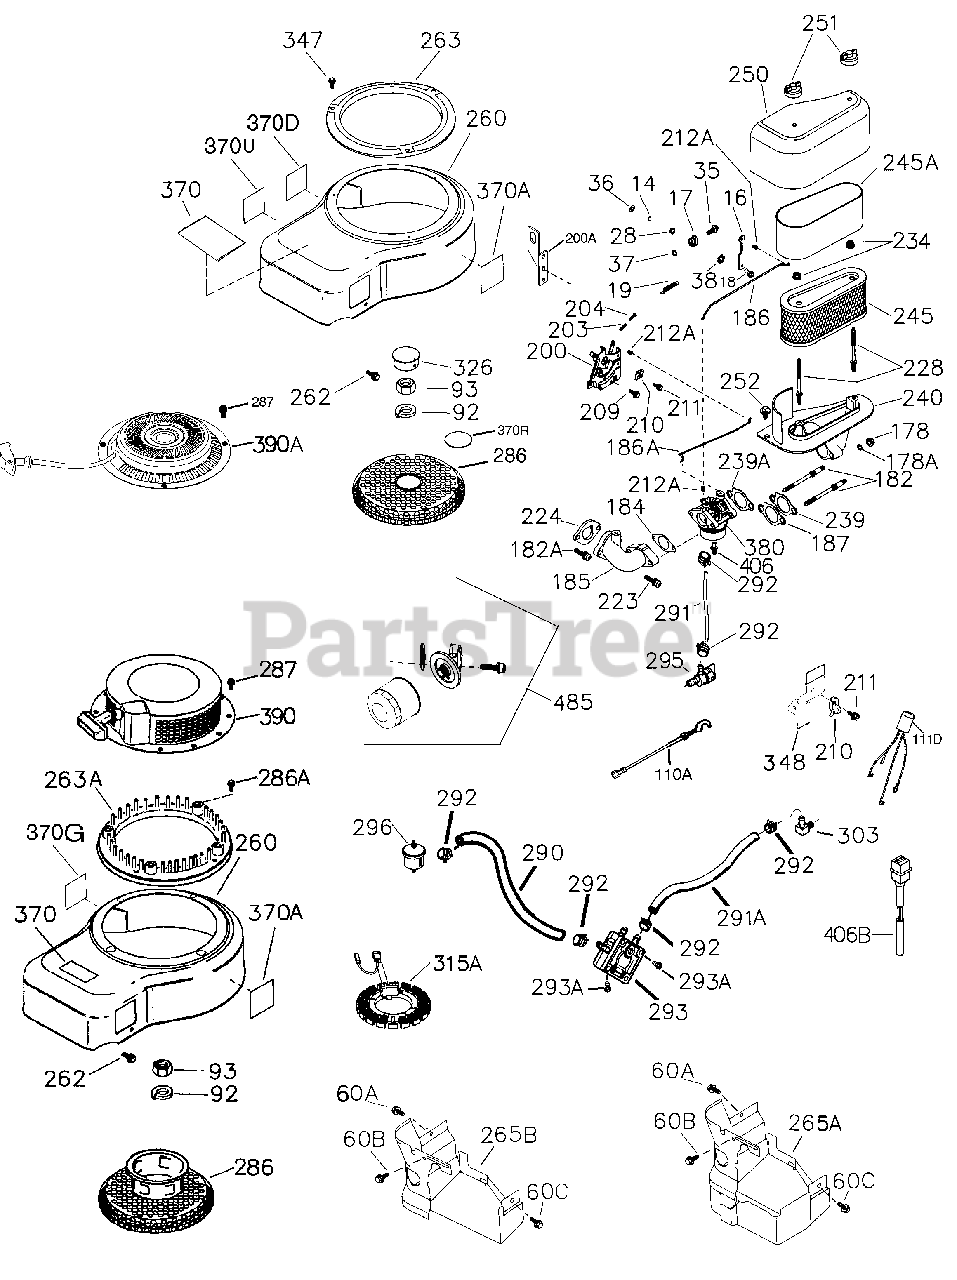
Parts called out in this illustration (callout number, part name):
14	Flat Washer
16	Governor Lever (Incl. 212A)
17	Governor Lever Clamp
18	Screw, T-15, 8-32 x 3/8"
19	Extension Spring
28	Lock Nut, 8-32
35	Screw, 10-32 x 3/4"
36	Lock Washer #8
37	Lock Nut, 10-32
38	Retaining Ring
60B	Screw, 10-24 x 1/2"
92	Lock Washer
93	Flywheel Nut
110A	Fuel Solenoid Wire - Green, 9.0''
130A	Screw, 5/16-18 x 17/32"
130B	Screw, 1/4-20 x 1/2"
163	Rocker Arm Bearing
178	Lock Nut, 1/4-20
182	Carburetor Mounting Stud
184	* Carburetor To Intake Pipe Gasket
185	Intake Pipe
186	Governor Link
200	Control Bracket Incl. 212A & 711
210	Conduit Clip
211	Screw, 10-32 x 3/8"
212A	Bushing
223	Screw, T-30, 5/16-18 x 1-9/32"
224	* Intake Spacer
228	Air Cleaner Stud
234	Nut & Lock Washer, 1/4-20
239	* Air Cleaner Gasket
240	Air Cleaner Body (Incl. 228 & 239)
243	Screw, 10-32 x 7/16"
245	Air Filter (Incl. 234) also available in Packaged Part #740055B
245A	Poly Pre-Filter (also available in Pa ckaged Part #740055B) also available in Packaged Part #740055B
250	Air Cleaner Cover
251	Wing Nut, 1/4-20
252	Screw, 1/4-20 x 19/32"
260	Blower Housing
263	Trim Ring
286	Cup & Screen
290	Fuel Line
292	Fuel Line Clamp
296	Fuel Filter (Incl. 292) also availabl e as Packaged Part #740003B
326	Screen Plug
347	Screw, 10-32 x 9/16"
348	Choke Bracket
365	Screw, 8-32 x 27/64"
370	Decal - Important Lubrication - SAE 3
380	Carburetor (Incl. 184 & 212A)
406	Fuel Shut-Off Solenoid
406A	Solenoid Spring
710	Compression Spring
711	Screw, 6-32 x 21/32"
